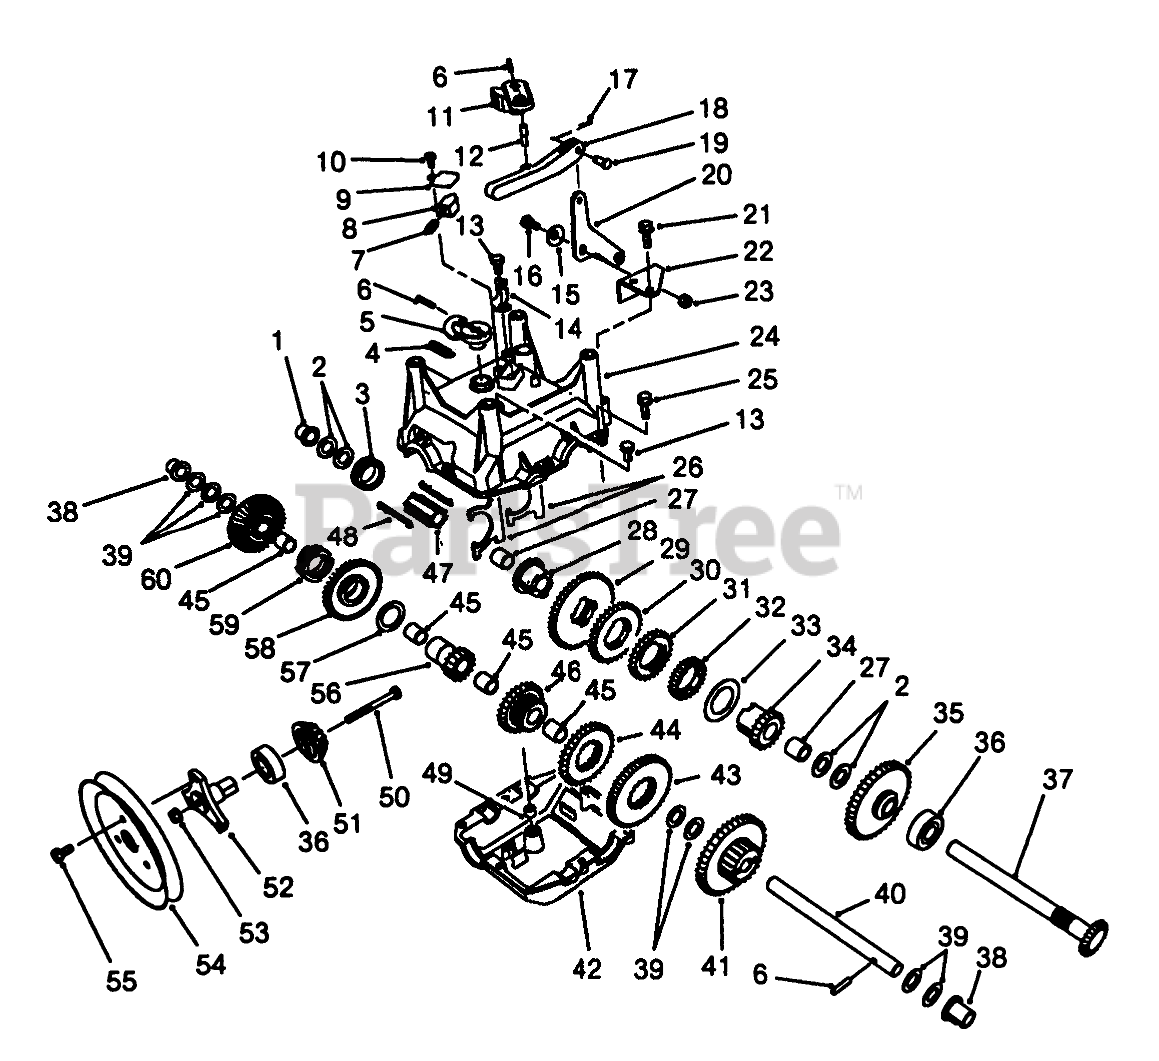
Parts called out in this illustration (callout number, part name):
1	BUSHING-FLANGE, OUTPUT
2	BEARING-THRUST
3	COLLAR-SHIFT
4	SPRING-EXTENSION
5	LEVER
6	PIN-SPRING
7	SPRING-DETENT
8	BUTTON-DETENT
9	COVER-DETENT
10	SCREW-HWH
11	LEVER-SHIFT, GEAR
12	PIN-LINK, GEAR SHIFT
13	SCREW-HWH
14	BRACKET-CABLE
15	WASHER-CURVED
16	SCREW-SHOULDER
17	PIN-COTTER
18	LINK-SHIFT, GEAR
19	PIN-CLEVIS
20	BELLCRANK
21	SCREW-HWH
22	BRACKET-BELLCRANK
23	NUT-LOCK, NI
24	GEARCASE-UPPER, CASING
26	YOKE-SHIFT
27	BUSHING-OUTPUT
28	SLEEVE-GEAR
29	GEAR-45 T
30	GEAR-34 T
31	GEAR-27 T
32	GEAR-29 T
33	WASHER-THRUST
34	GEAR-SLEEVE, 19 T
35	GEAR-41 T
36	BEARING-BALL
37	SHAFT-OUTPUT
38	BUSHING-INTERMEDIATE
39	WASHER-THRUST
40	SHAFT-INTERMEDIATE
41	GEAR-19/41 T
42	GEARCASE-LOWER, CASING
43	GEAR-51 T
44	GEAR-33 T
45	Bushing-Output
46	Gear-26T
47	Sleeve-Shift
48	KEY-SHIFT
49	BUSHING-YOKE
50	SCREW-HH
51	PINION-BEVEL
52	HUB-PULLEY
53	NUT-HHF
54	TRACTION-SHEAVE, HALF
55	SCREW
56	GEAR-BEVEL, 15 T
57	WASHER-THRUST
58	Gear-Bevel 36T
59	Collar-Shift
60	Gear-Bevel Reverse 36T
